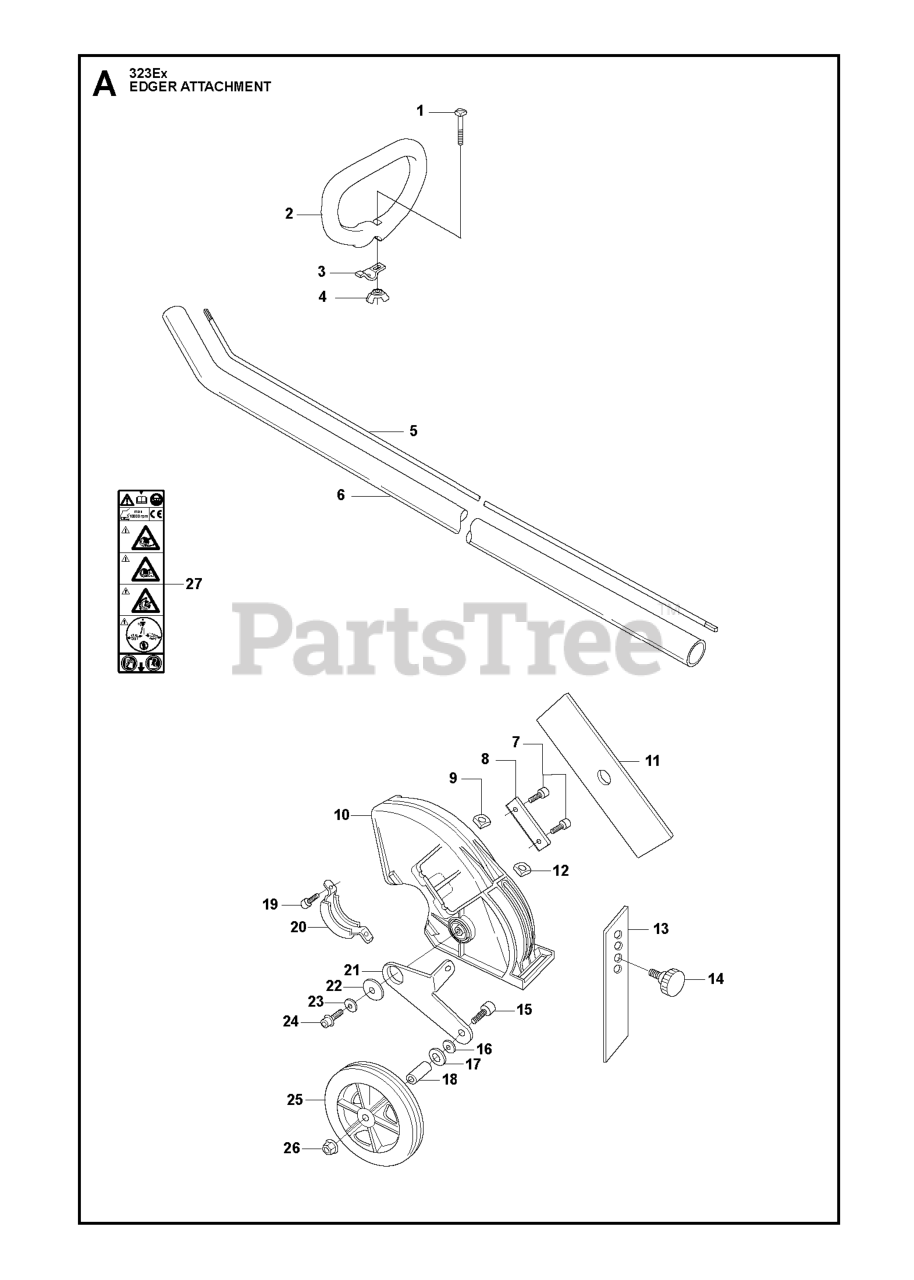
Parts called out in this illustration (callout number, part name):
2	HANDLE, LOOP
3	HOLDER
5	SHAFT
6	PIPE
10	BLADE PROTECTOR
11	BLADE 7.52X2X.125
13	RUBBER PROTECTOR, EDGER
16	WASHER BRB 8.4X17
24	SCREW
25	WHEEL, EDGER
26	NUT M8 FLANGE
27	LABEL WARNING
